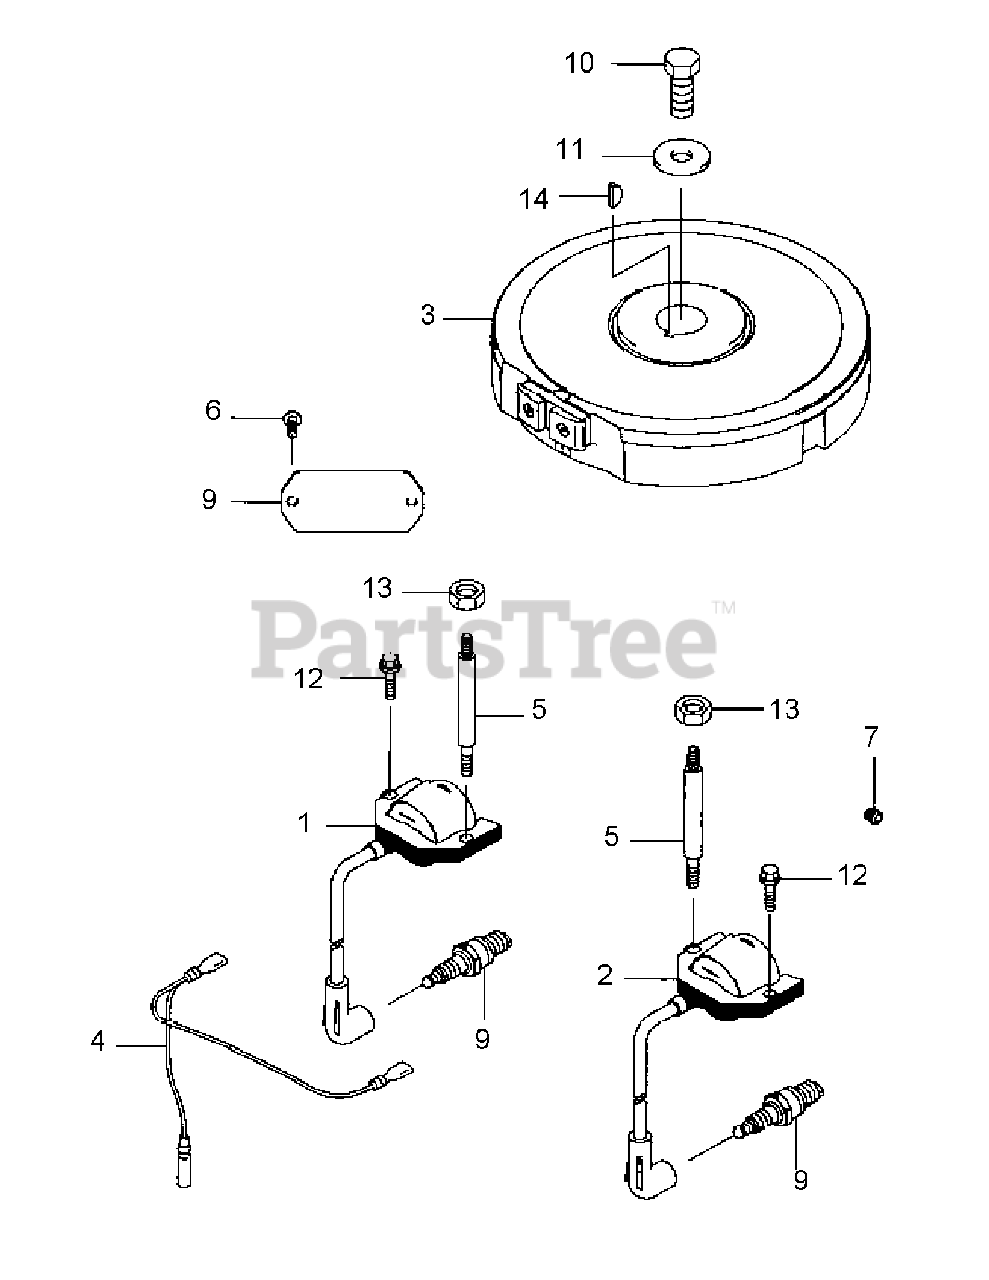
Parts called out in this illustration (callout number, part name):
1	IGNITION COIL ASSY.
2	IGNITION COIL ASSY.
9	SPARK PLUG
12	FLANGED BOLT
14	WOODRUFF KEY
